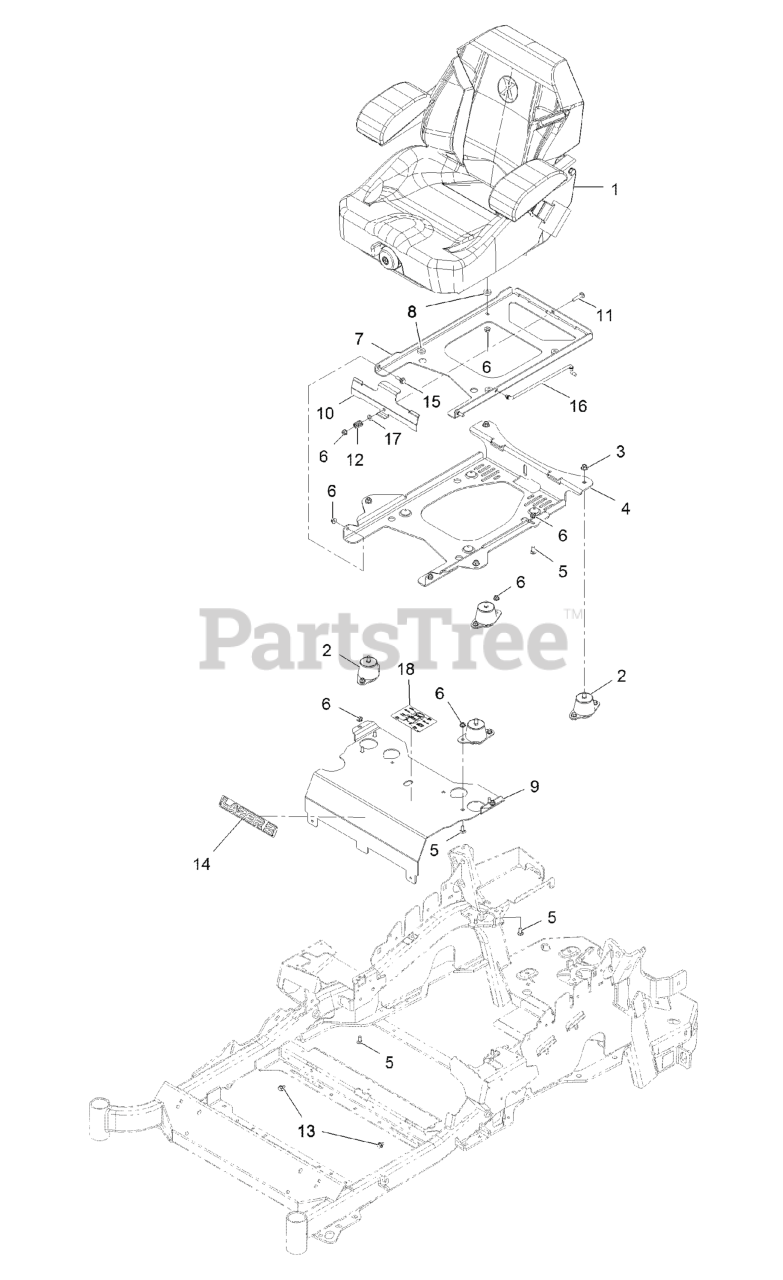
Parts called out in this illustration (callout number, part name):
1	KIT-SUSPENSION SEAT
2	ISOLATOR-SEAT
3	NUT-HF, NI
4	PLATE-TILT, SEAT SUPPORT
5	SCREW-CARR
6	NUT-HF, NI
7	PLATE-FRAME, SEAT
9	Panel-Front, Seat Mount
10	PLATE-LATCH, SEAT
11	BOLT-CARR
12	SPRING-COMPRESSION
14	DECAL, LAZER MODEL
15	SCREW-SHOULDER
16	ROD-PROP
17	WASHER-PLAIN
18	DECAL-SERVICE AID
